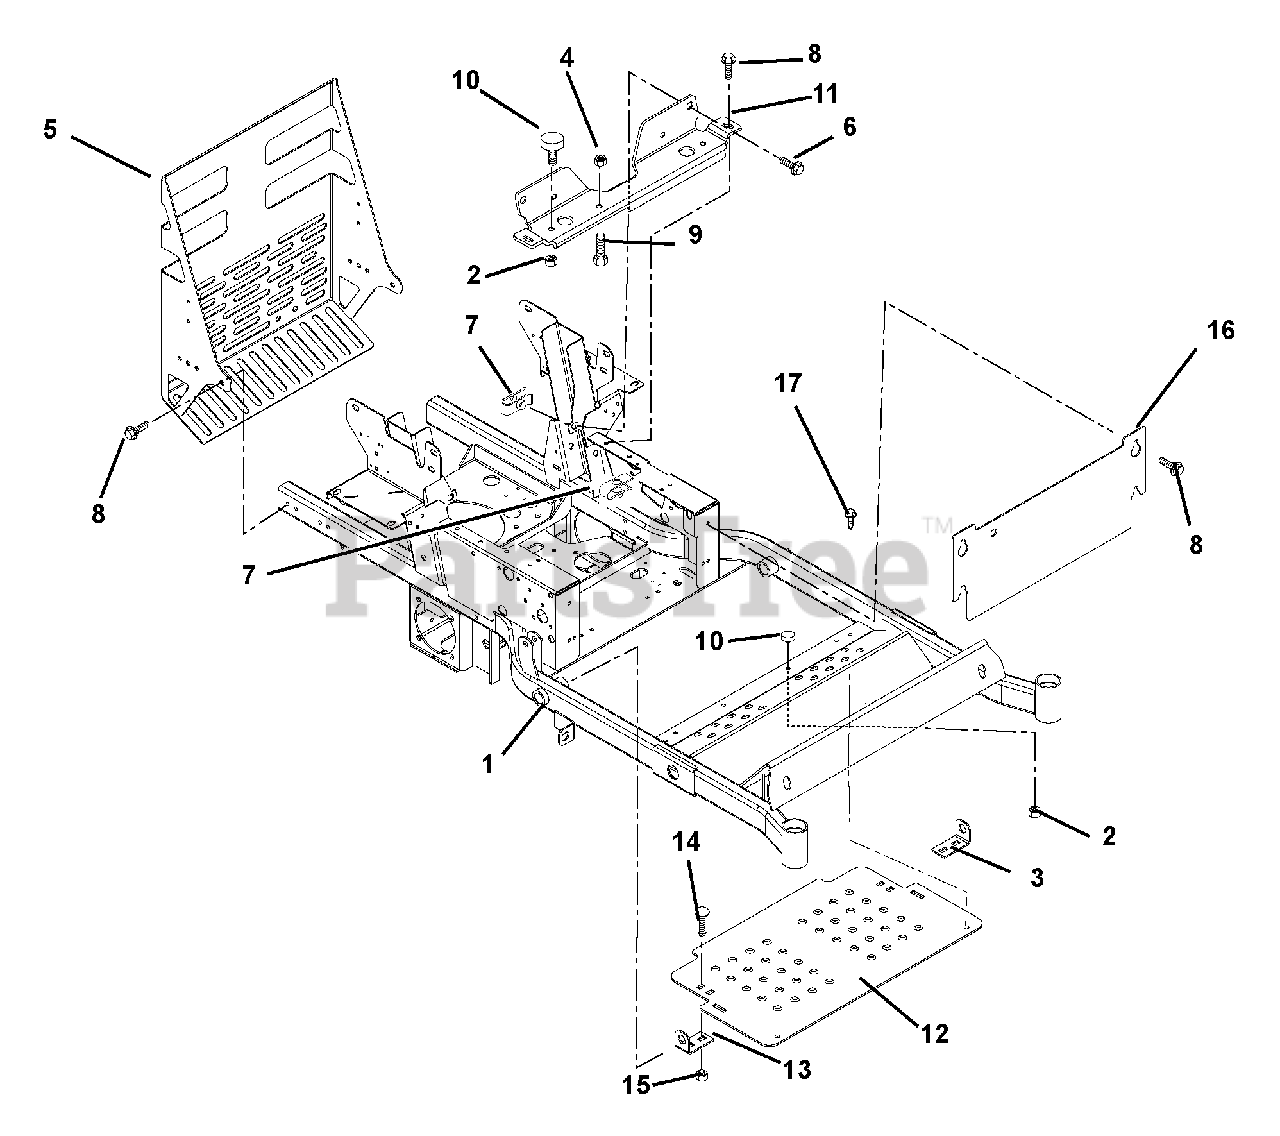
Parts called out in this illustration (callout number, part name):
1	WMT, 44", 48", 52" IZ FRAME
2	@NUT-SPNLK-FLG .312-18 YWZC
3	HINGE, FOOTBOARD LH
4	@NUT-LK-TOP-FLG .31-18 YWZC
5	WMT, BUMPER W/ HEAT SHIELD
6	BLT-SERHFWH .375-16X1.0 YWZC
7	NUT-RTNR .375-16X.37
8	@SCR-TAP .38-16X.50 HWH TR YWZ
9	@BLT-HEX .31-18X1.25 GR5 YWZC
10	BUMPER, RUBBER
11	SEAT SUPPORT - BLACK
12	PANEL, INSPECTION
13	HINGE, FOOTBOARD RH
14	@BLT-RDHDSQNK .38-16X.75 G5YZ
15	@NUT-LK-TOP-FLG .38-16 YWZC
16	ACCESS PANEL - ORANGE
17	@SCR-TAP .38-16X1.00 HWH TR YZ
